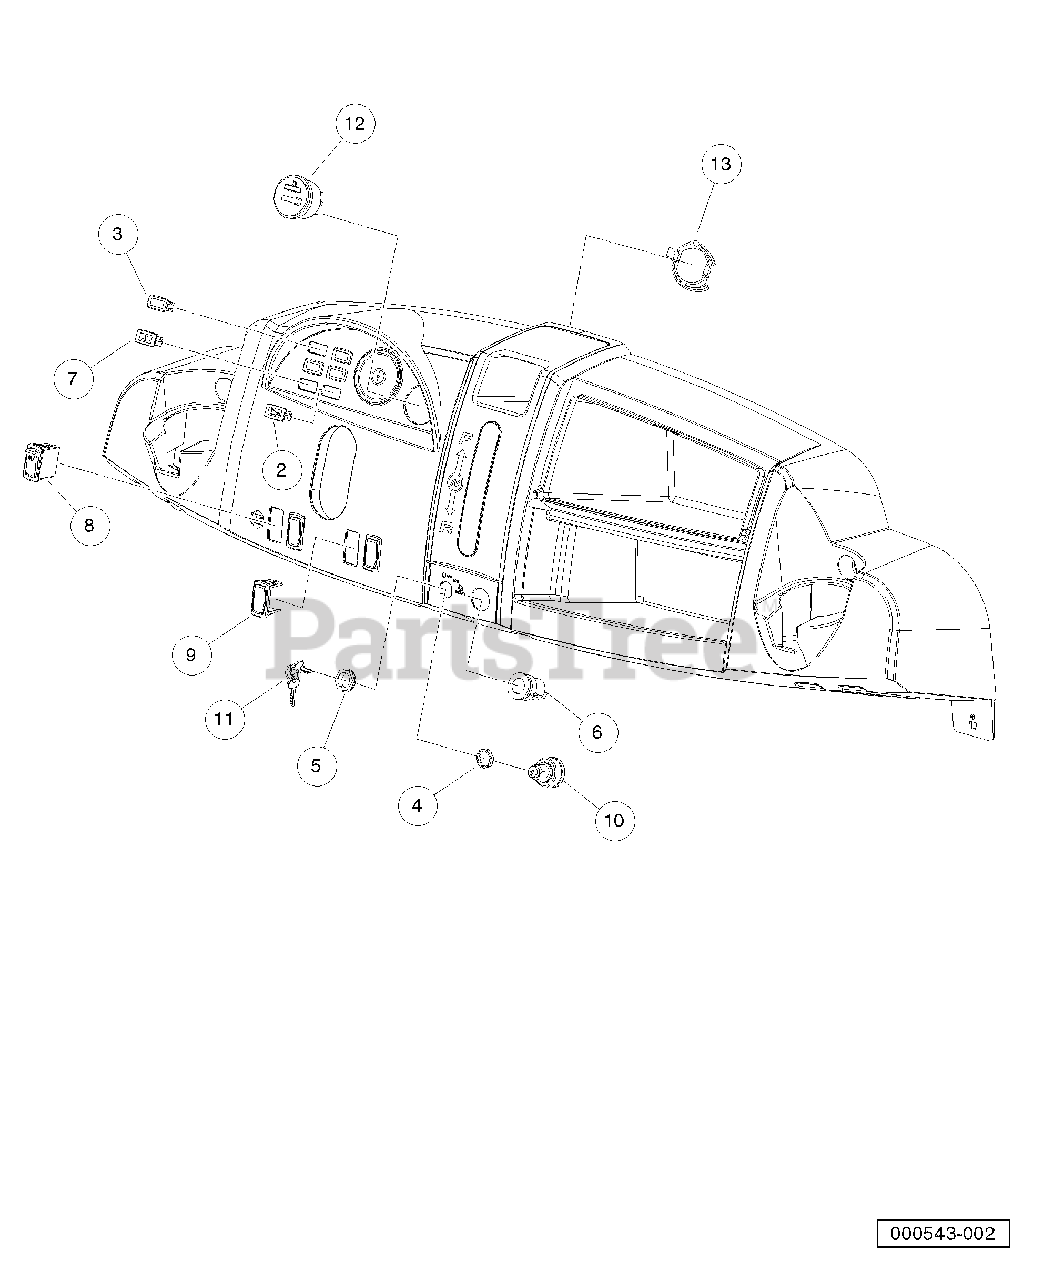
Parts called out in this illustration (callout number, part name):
1	Instl, Elec Sys, Restyle Diesl
2	Light, Oil
3	Plug, Hole
4	Spacer, Keyswitch
5	Nut, Key Switch
6	Receptacle, Accessory
7	Light, Indicator, Coolant Temp
8	Switch, Rocker, Light
9	Cover, Hole, Switch, Rocker
10	Keyswitch, 12v, Diesel
11	Keys
12	Gauge Fuel-hour Sep Gnd
13	Clip, Meter, Round
